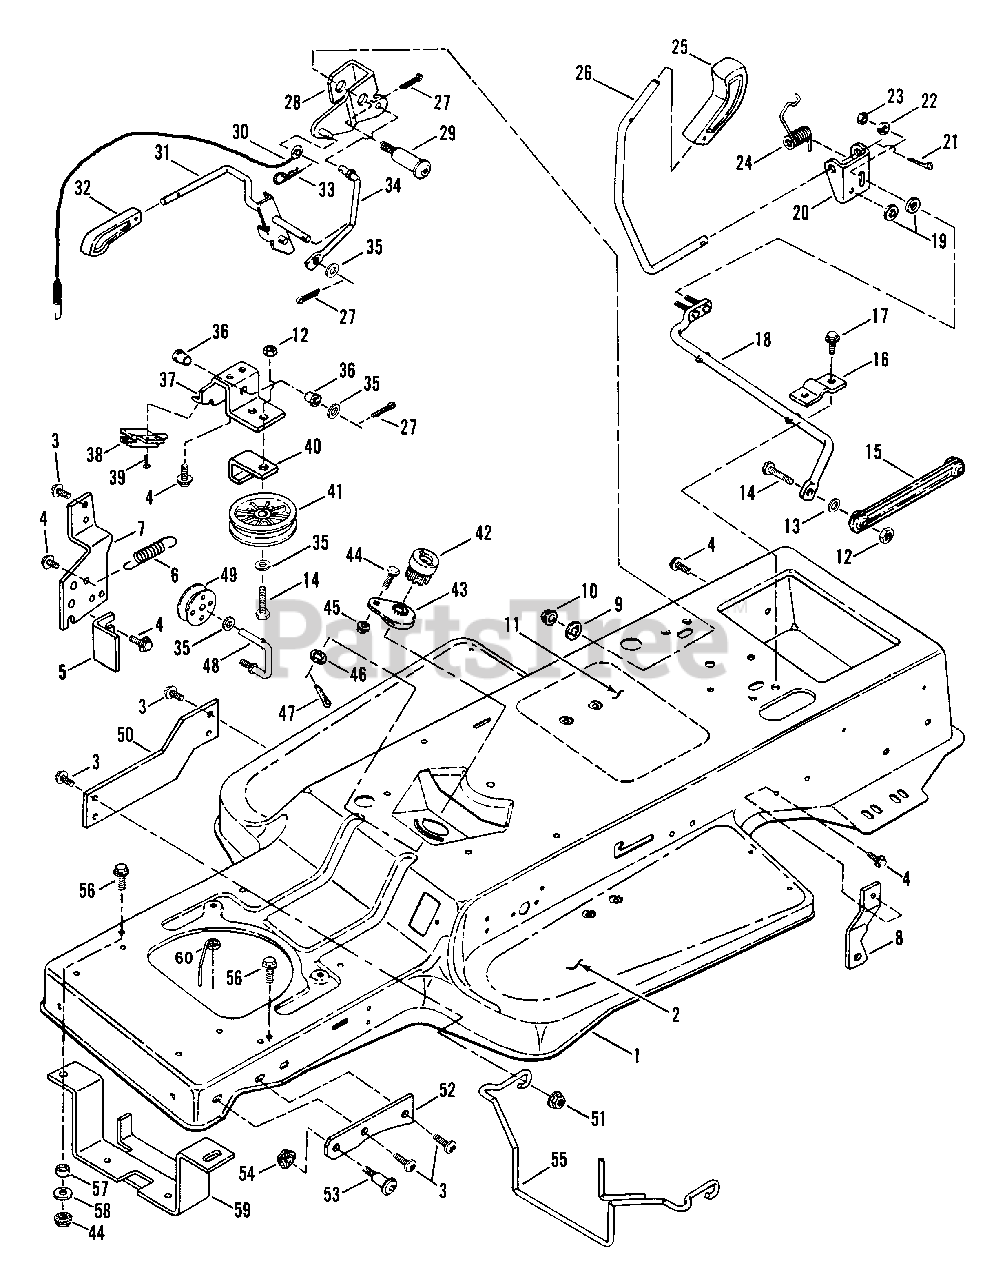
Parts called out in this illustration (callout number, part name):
1	FRAME, Tractor
2	FOOTPAD, Deluxe
3	SCREW, 5/16-18 x 5/8" Truss Head (Torx)
4	SCREW, 5/16-18 x 5/8" Hex Washer Head
5	GUIDE, Cable
6	SPRING, Brake Return
7	BRACKET, Axle/Spool
8	BRACKET, Torque
9	WASHER, 1/2 Internal Tooth Lock
10	NUT, 1/2-13 Hex Flange Lock
11	DECAL, Instruction/SAFETY
12	NUT, 3/8-16 Hex Center Lock
13	SPACER
14	SCREW, 3/8-16 x 1 1/2" Hex Head Cap
15	LINK, Shift Lever
16	CLIP, Shift Lever
17	SCREW, 5/16-18 x 1 1/4" Self-Tapping
18	ASSEMBLY, Shift Lever (Lower)
19	WASHER, 5/16" Internal Tooth Lock
20	BRACKET, Shift Lever (Upper)
21	COTTER-PIN, 5/32 x 1"
22	WASHER, 1/4 Flat
23	NUT, 14-20 Hex Nyloc
24	SPRING, Shift Lever
25	KNOB, Deck Lift Lever
26	LEVER, Shift
27	COTTER-PIN, 3/32 x 3/4"
28	WELDMENT, PTO Bellcrank
29	BOLT, 1/2-13 x 2 11/32" Shoulder
30	CABLE, Blade 21.5" Long
30	CABLE, Blade 19.75" Long
31	WELDMENT, PTO Lever
32	KNOB, PTO Lever
33	PIN, Hair, 3/32 x 1 1/2"
34	ROD, PTO Link
35	WASHER, 3/8" Flat
36	BUSHING
37	SUPPORT, PTO Lever
38	SWITCH, Blade Engagement
39	SCREW, #10-24 x 1/2" Hex Washer Self-Tap (Torx)
40	GUIDE, Belt
41	PULLEY
42	GEAR, Steering Pinion
43	ASSEMBLY, Steering Adjuster
44	BOLT, 1/4-20 x 5/8" Short Neck Carriage
45	NUT, 1/4-20 Hex Flange Lock
46	WASHER, 1/2 Shim
47	COTTER-PIN, 1/8 x 3/4"
48	ROD, Spool Pivot
49	SPOOL
50	BRACE, Frame
51	NUT, 5/16-18 Hex Flange Lock
52	BRACKET, Hood Pivot
53	BOLT, 3/8-16 x 1 1/4" Shoulder
54	NUT, 3/8-16 Hex Flange Lock
55	GUIDE, Belt
56	BOLT, 5/16-18 x 1 1/4" Hex Washer Head
57	SPACER
58	WASHER, 13/32 x 3/4" Flat
59	WELDMENT, Belt Guide
60	GUIDE, Belt
